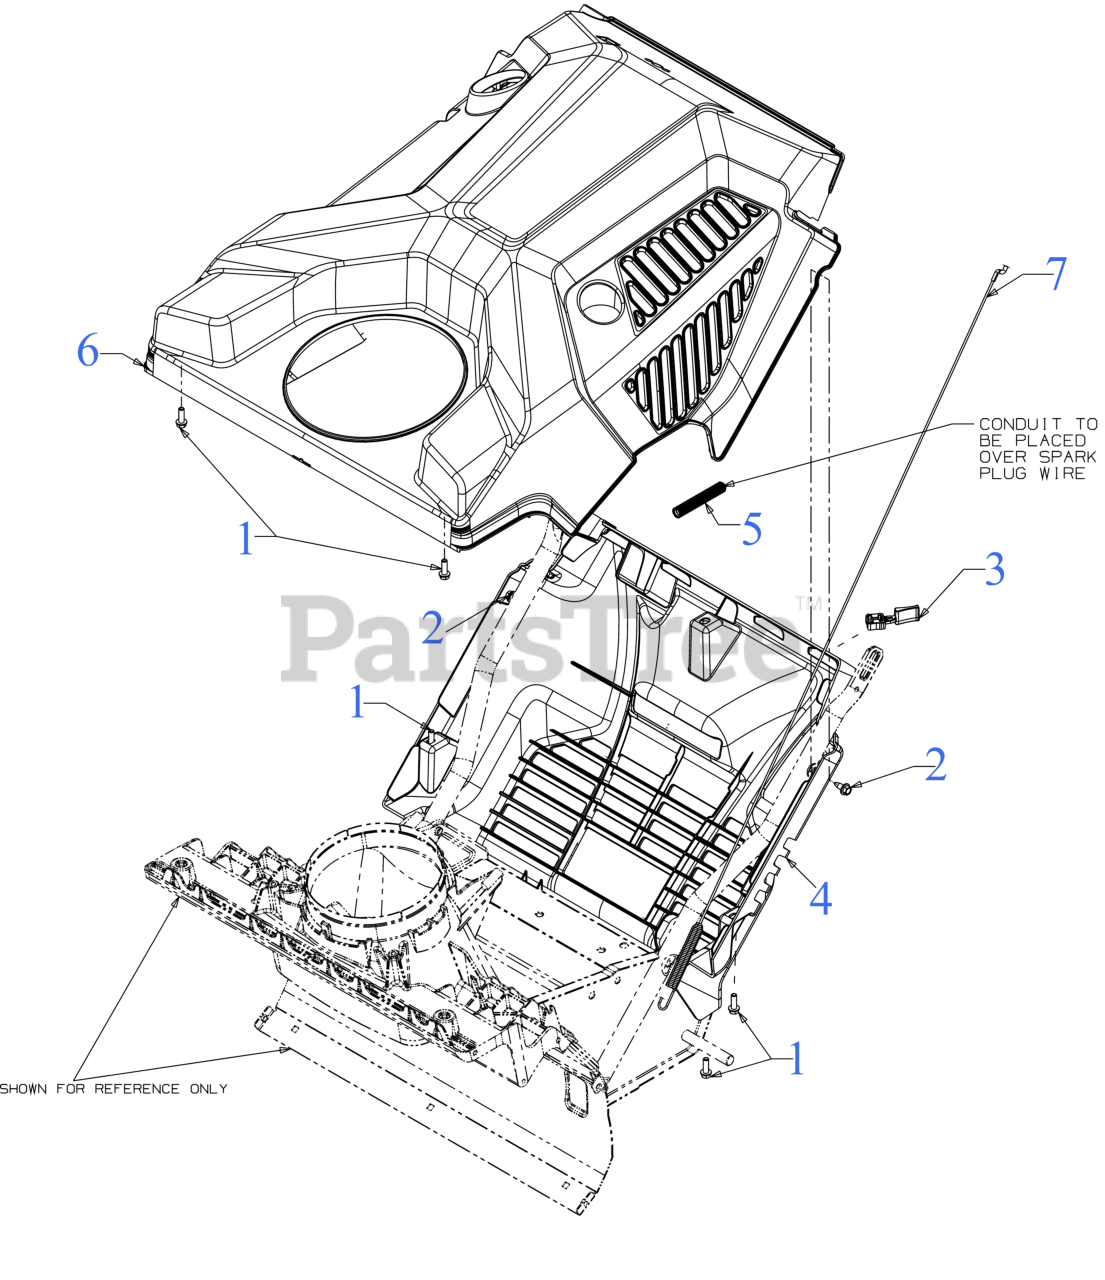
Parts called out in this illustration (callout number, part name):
1	SCREW 1/4-15 x .750
2	SCREW 1/4-20X.625
3	CHOKE EXTENION LEVER
4	BOTTOM COVER
5	CONVOLUTED CONDUIT
6	TOP COVER (H STY-YLW W/O HDLT)
7	AUGER CLUTCH CABLE 37.05"
